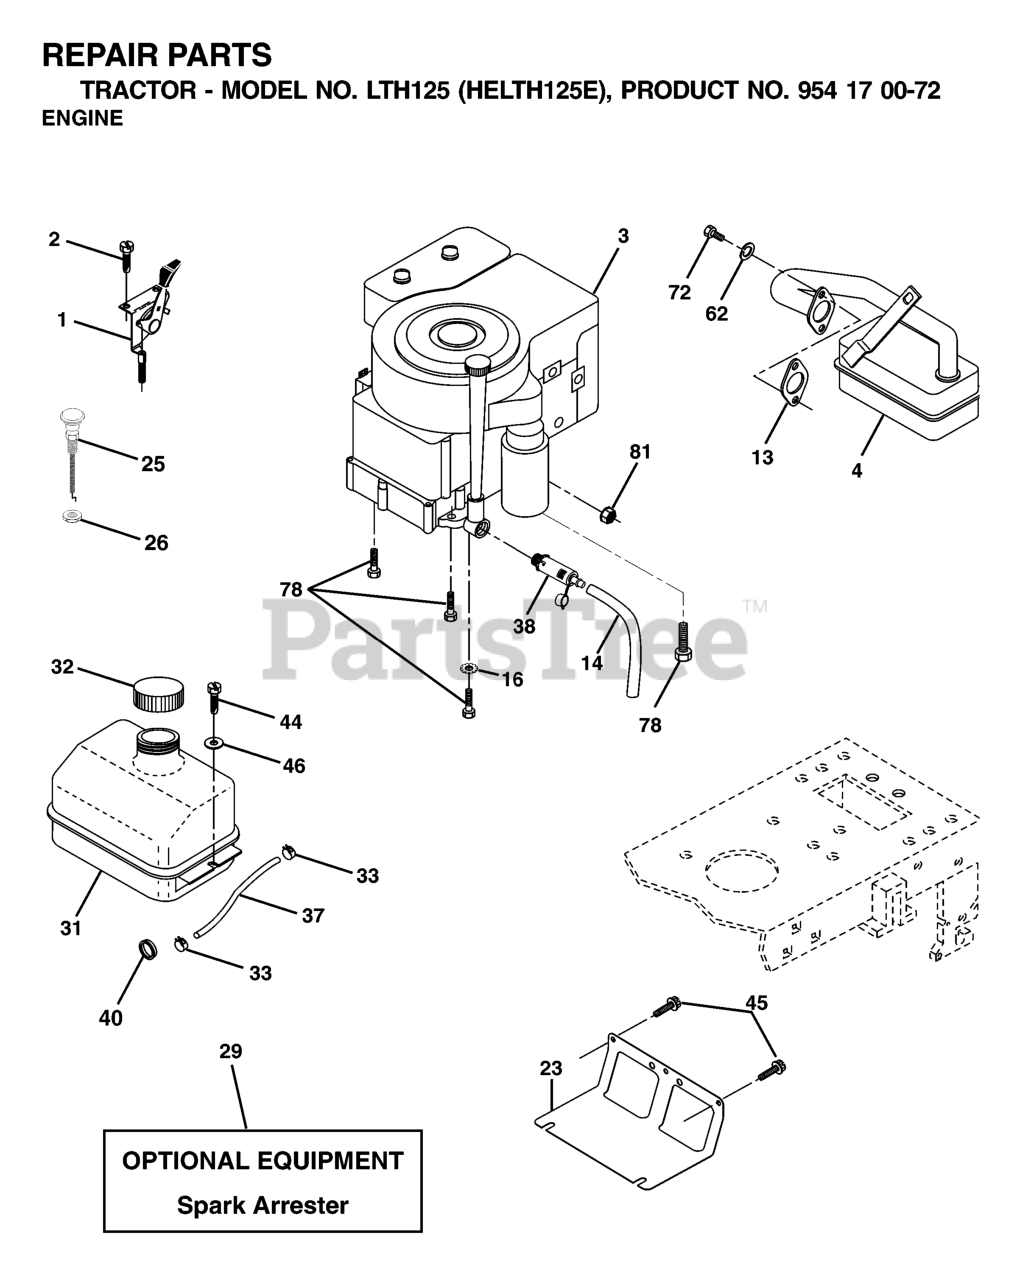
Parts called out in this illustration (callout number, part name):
1	CONTROL.THROTTLE/CHOKE.BLACK
2	SCREW
4	MUFFLER.SINGLE.B&S.10-12HP
13	REPL BY 532 27 22-93
14	TUBE, DRAIN OIL ASM.
16	LOCKWASHER
23	SHIELD.BROWNING.DBR.GUARD
26	Nut Keps 3/8 - 24 UNF
29	KIT.SPARK ARRESTOR 794945 B&S
31	TANK FUEL LT
32	FUEL CAP
33	HOSE CLAMP
37	LINE.FUEL.20
38	PLUG, OIL DRAIN EASY
40	BUSHING.SNAP.NYL.BLK.
44	SCREW HEXWSHR 1/4-20X3/4
45	SCREW, 3/8-16X3/4
46	WASHER
62	WASHER.LOCK.HVY.HLCL.SPR.5/16
72	SCREW
78	SCREW.3/8-16
81	NUT
